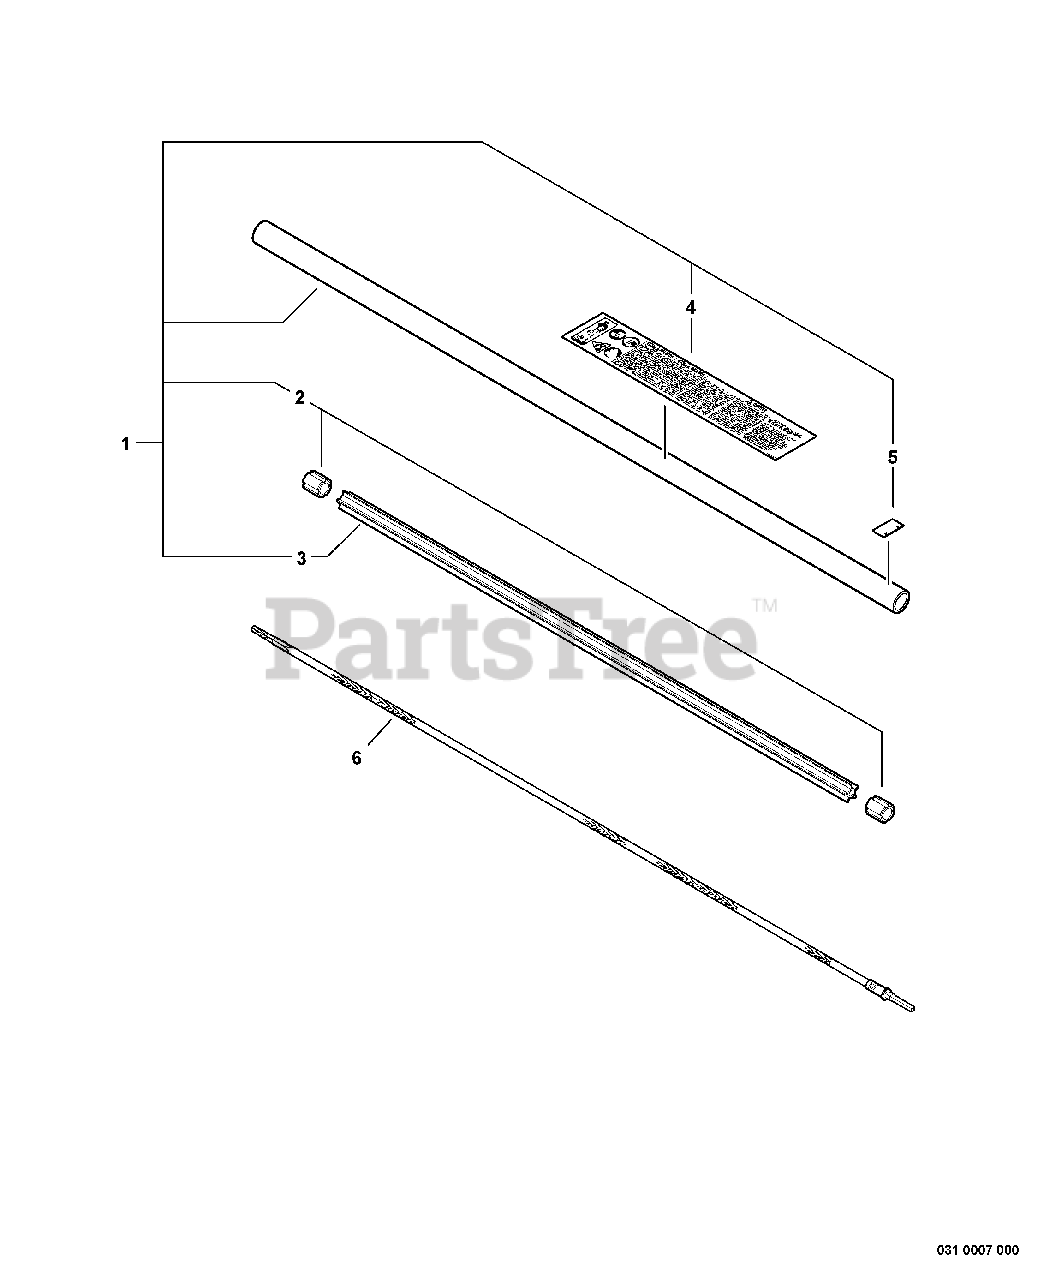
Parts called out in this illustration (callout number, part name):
1	MAIN PIPE ASSY
3	LINER - FLEXIBLE
4	LABEL, CAUTION
5	LABEL - ALIGNMENT
6	DRIVESHAFT - FLEXIBLE
